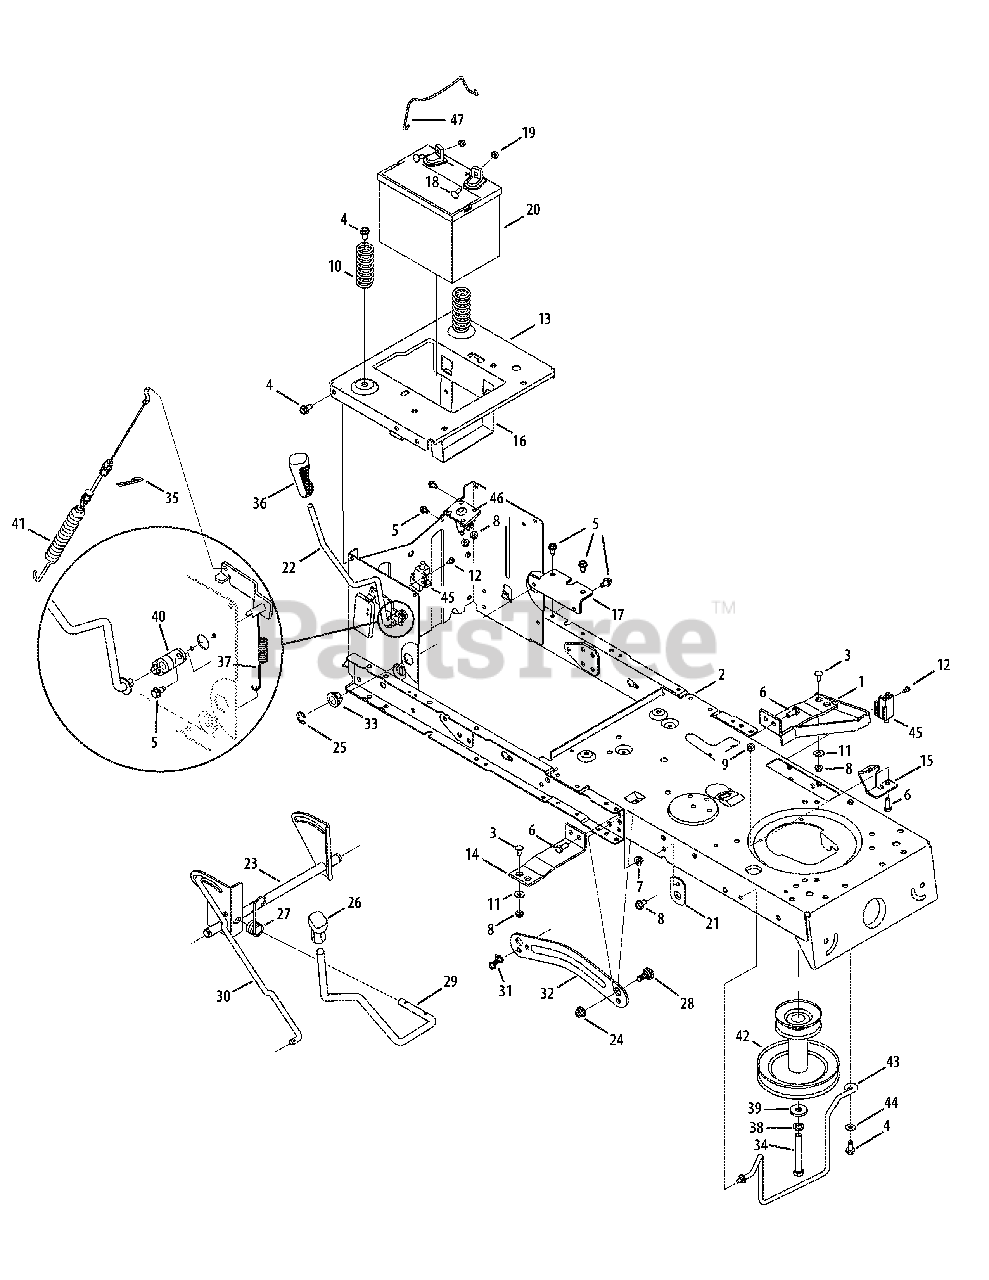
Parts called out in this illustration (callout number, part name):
1	Support Bracket
2	Frame Assembly
3	Screw Carriage, 1/4-20 x .62
4	Screw 5/16-18 x .750
5	Screw, 1/4-20 x .500
6	Hex Screw, 5/16-18 x .75
7	Flange Lock Nut, 5/16-18
8	Flange Lock Nut, 1/4-20
9	Hexlock Nut, 5/16-18
10	Compression Spacer, 1.28 x 3.125
11	Flat Washer, .28 x .74 x .063
12	Shoulder Spacer, 10-32 x .500
13	Seat Frame Bracket
14	Running Board Bracket
15	Support Frame Bracket
16	Battery Bracket
17	Brace Frame Bracket
18	Hex Head Flange, 1/4-20 x .75
19	Sems Nut, 1/4-20
20	230 CCA Battery
21	Support Bracket
22	PTO Handle Assembly
23	Lift Assembly
24	Flange Lock Nut, 3/8-16
25	E Ring
26	Handle Grip, 1/2
27	Torsion Spring
28	Shoulder Bolt, 3/8-16 x .625 x .175
29	Deck Lift Handle
30	Lift Rod
31	Bow-tie Cotter Pin
32	Lift Arm, RH
32	Lift Arm, LH
33	Hex Flange Bearing
34	Hex Screw, 7/16-20 x 3.25, 38/42"
35	Click Pin, .092 x 1.64
36	Handle Grip, 3/8
37	PTO Spring Extension
38	Regular Duty Washer Lock, 7/16
39	Flat Washer, .450 x 1.250 x .164
40	PTO Bearing
41	Deck Engage Cable
42	Engine Pulley, 3.39 x 6.12, 38/42"
43	Belt Keeper
44	Flat Washer, .406 x .875 x .059
45	Switch Interlock
46	12V Solenoid
47	Rod Asm, Batt, Lt-5
